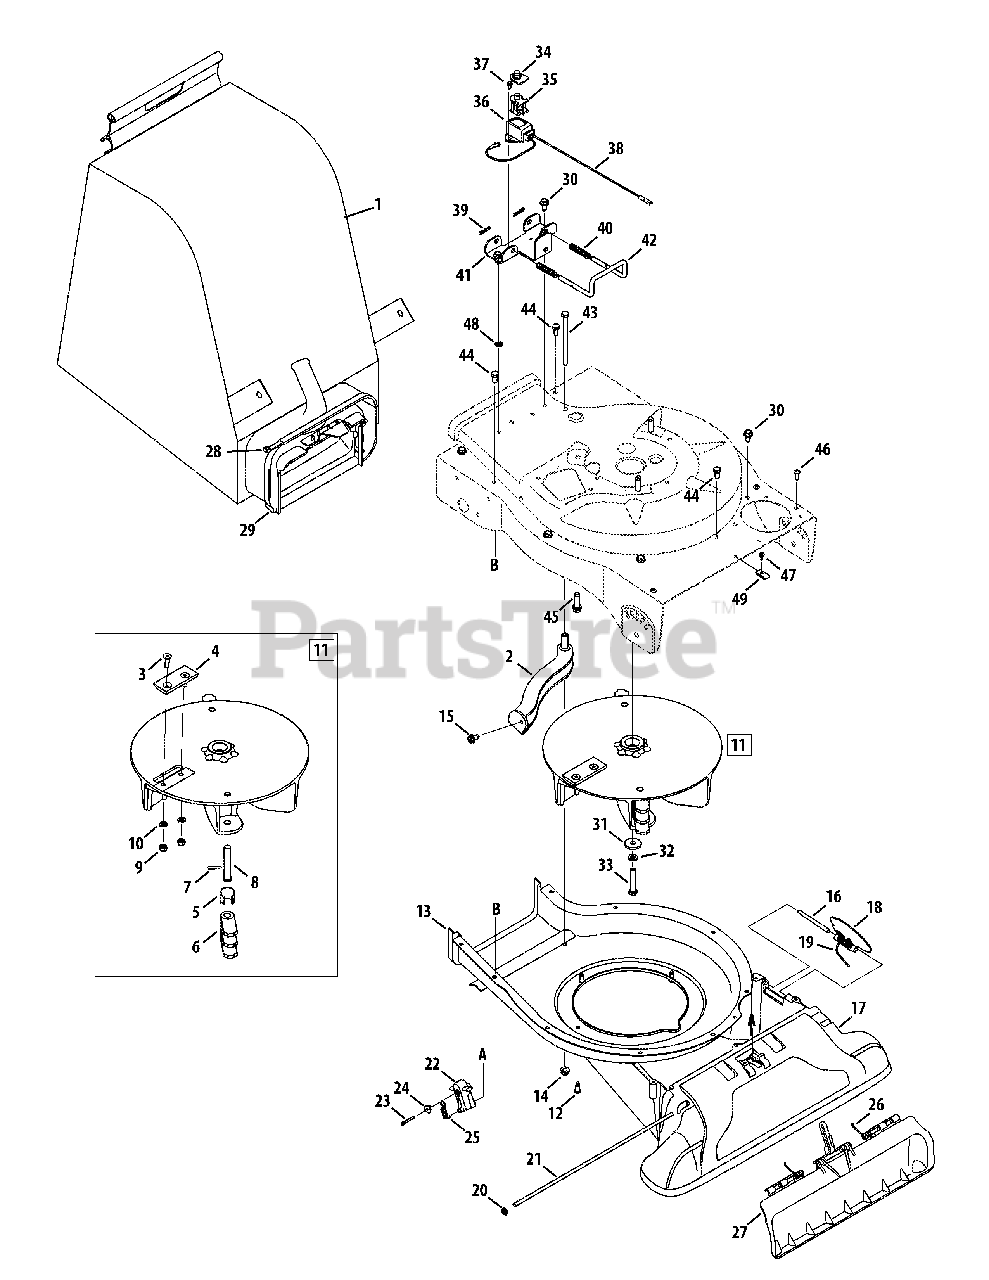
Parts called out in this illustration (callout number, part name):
1	Bag Assembly, Troy Bilt
1	Bag Assembly, Black
2	Screen Assembly
3	Hex Screw 5/16-24 x 1.0
4	Chipper Blade
7	Spiral Pin
8	Clevis Pin
9	Lock Nut, 5/16-24
10	Lock Washer, 5/16
11	Impeller Assembly
12	Shoulder Screw, #12-24 x.30 x.46
13	Lower Flail Housing
14	Flange Lock Nut 5/16-18
15	Screw, 5/16-18 x.500
17	Nozzle, Blk
18	Base Adapter Door
19	Torsion Spring
20	Cap Speed Nut 1/4
21	Pivot Rod
22	Nozzle Door Lever, Red
22	Nozzle Door Lever, Blk
23	Hex Screw, #8-18 x 1.25
24	Shoulder Spacer
25	Extension Spring
26	Nozzle Door Torsion Spring
27	Nozzle Door
28	Bag, TB Logo
29	Chute Assembly
30	Hex Index Screw, 5/16-12 x.750
31	Flat Washer.375 ID x 1.25 OD
32	Lock Washer 3/8
33	Hex Cap Screw 3/8-24 x 2.0
34	Switch Cover
35	Safety Switch
36	Safety Switch Cover
37	Hex Washer Screw #10-16 x.50
38	Wire Harness
39	Cotter Pin
40	Compression Spring
41	Mounting Bracket
43	Hex Cap Screw 5/16-18 x 4.5
44	Hex Cap Screw 5/16-18 x.625
45	Screw 3/8-16 x 1.00
46	Screw, #12-16 x.750
47	Screw #10 - 16 x.500
48	External L-Washer 5/16
49	Speed Nut
